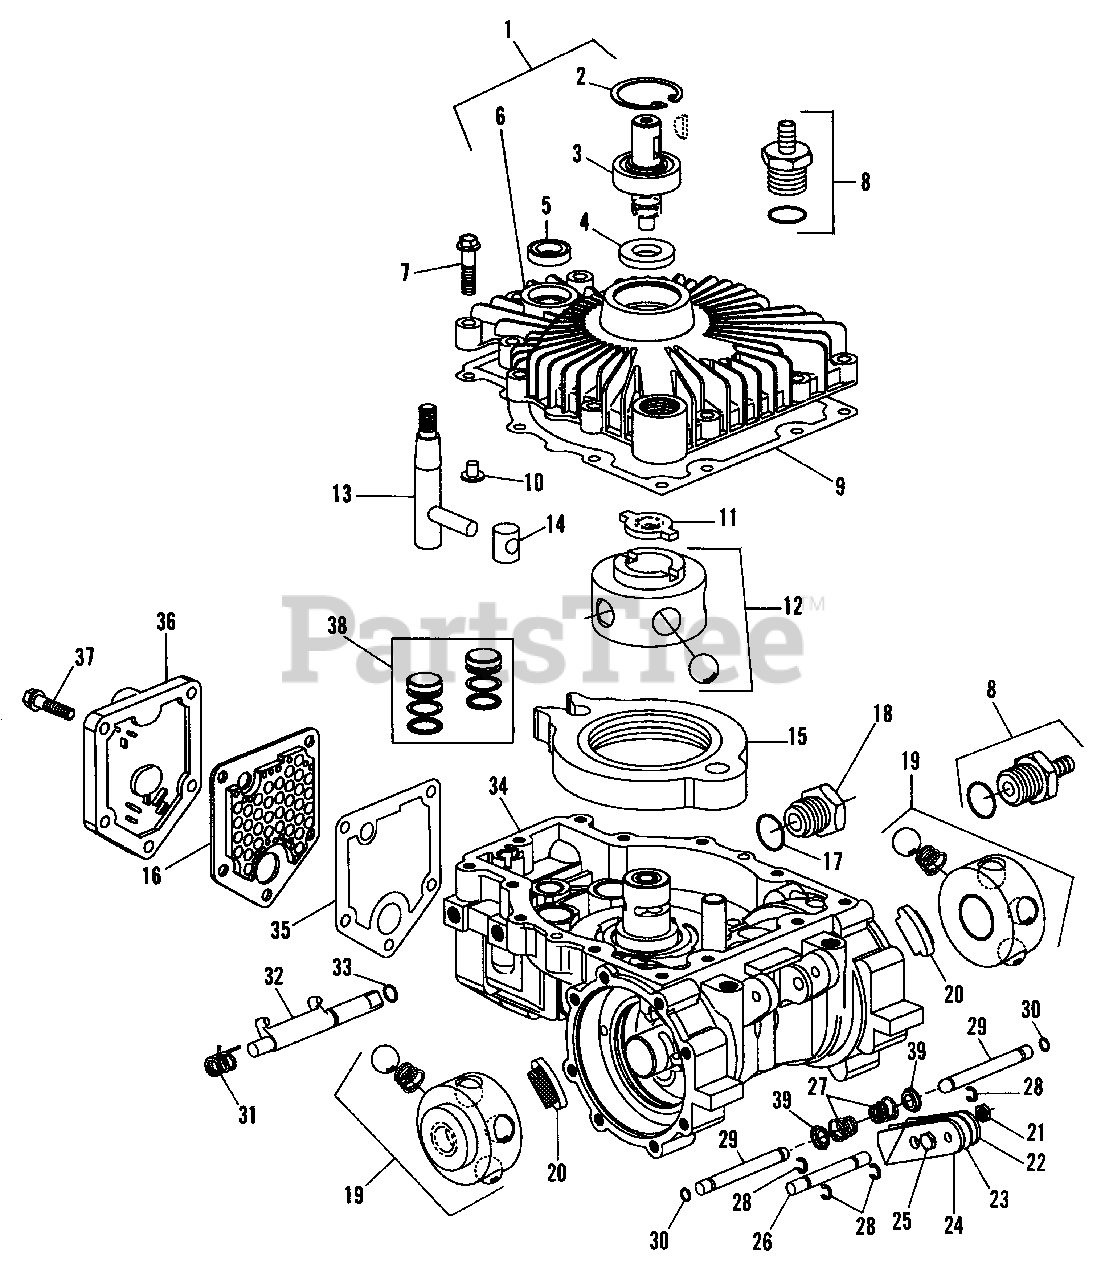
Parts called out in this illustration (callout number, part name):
1	COVER ASSY. (Incl. Ref. Nos. 2, 3, 4, 5 & 6)
2	RING, Ret, External
3	SHAFT ASSY, Input
4	SEAL, Input Shaft
5	SEAL, Control Shaft
7	SELF-TAP SCREW, .25-20
8	O-RING BARB FITTING ASSY.
9	COVER GASKET
12	PUMP, Rotor-Ball
13	CONTROL SHAFT
16	FILTER, Hydraulic
19	MOTOR ROTOR-BALL, 18 Teeth
20	PAD, Friction
21	NUT, Hex, Lock
22	LEVER, Brake, LH
24	LEVER, Brake, RH
25	SCREW, Cap, Hex
26	SHAFT, Brake
27	SPRING, Conical
31	SPRING, Dump Valve
35	VALVE COVER GASKET
36	VALVE COVER
37	CAPSCREW, Hex, Flange, 1/4-20
38	PISTON, Quieting
39	SPRING BASE
